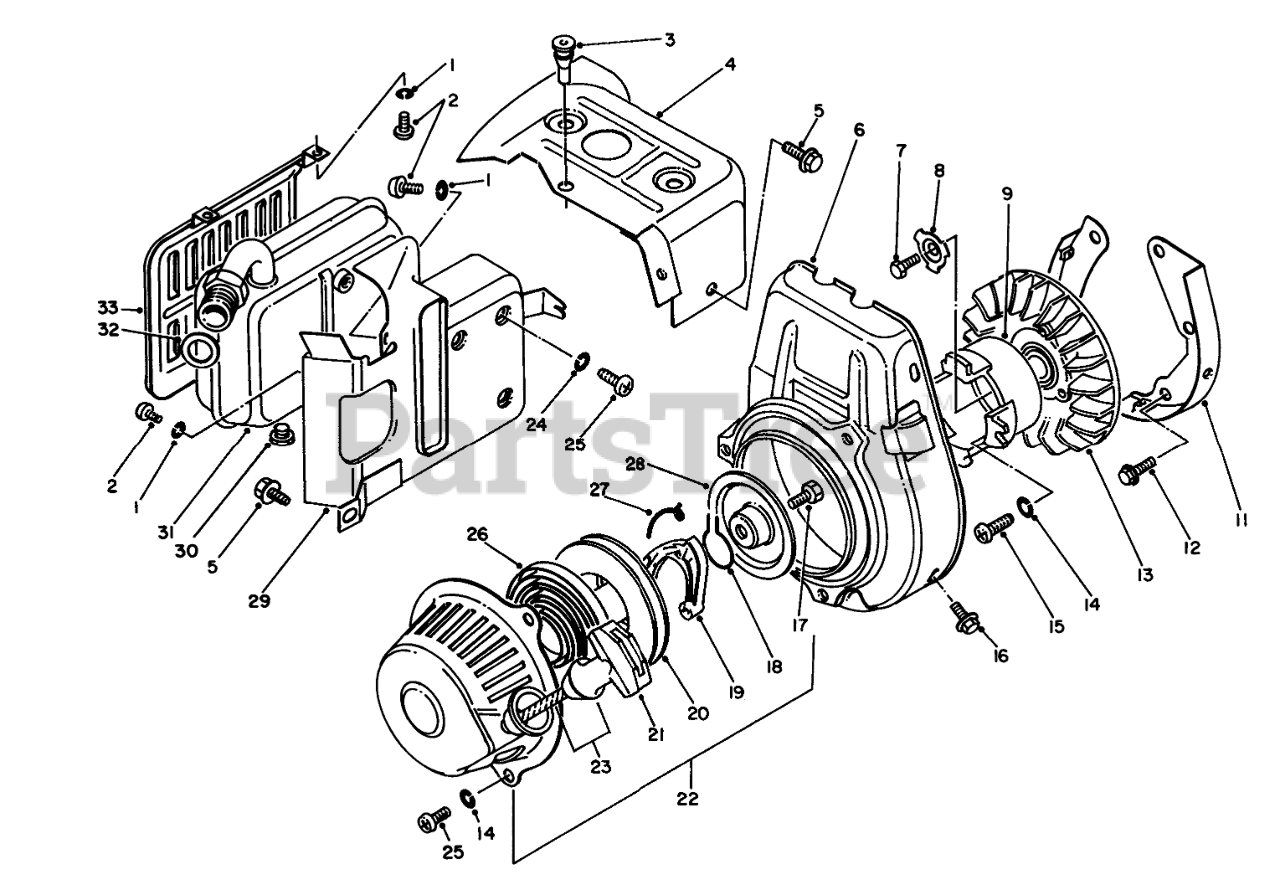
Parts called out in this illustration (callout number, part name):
1	Washer
2	Screw
3	Cushion
4	Cowling-Ventilation
6	COOLING FAN COVER
8	Washer
9	STARTER ASM
11	Plate-Cooling Fan Front
13	Fan-Cooling
14	LOCKWASHER
15	Screw
18	Spring
19	Ratchet
22	Starter Assembly-Recoil
23	Grip Assy. (Incl. Ref. #211)
25	Screw
26	Spring
27	Spring-Return
28	Plate-Friction
29	Cover-Rear
30	Plug-Drain
31	Muffler
32	Gasket-Exhaust
33	Cover-Front
